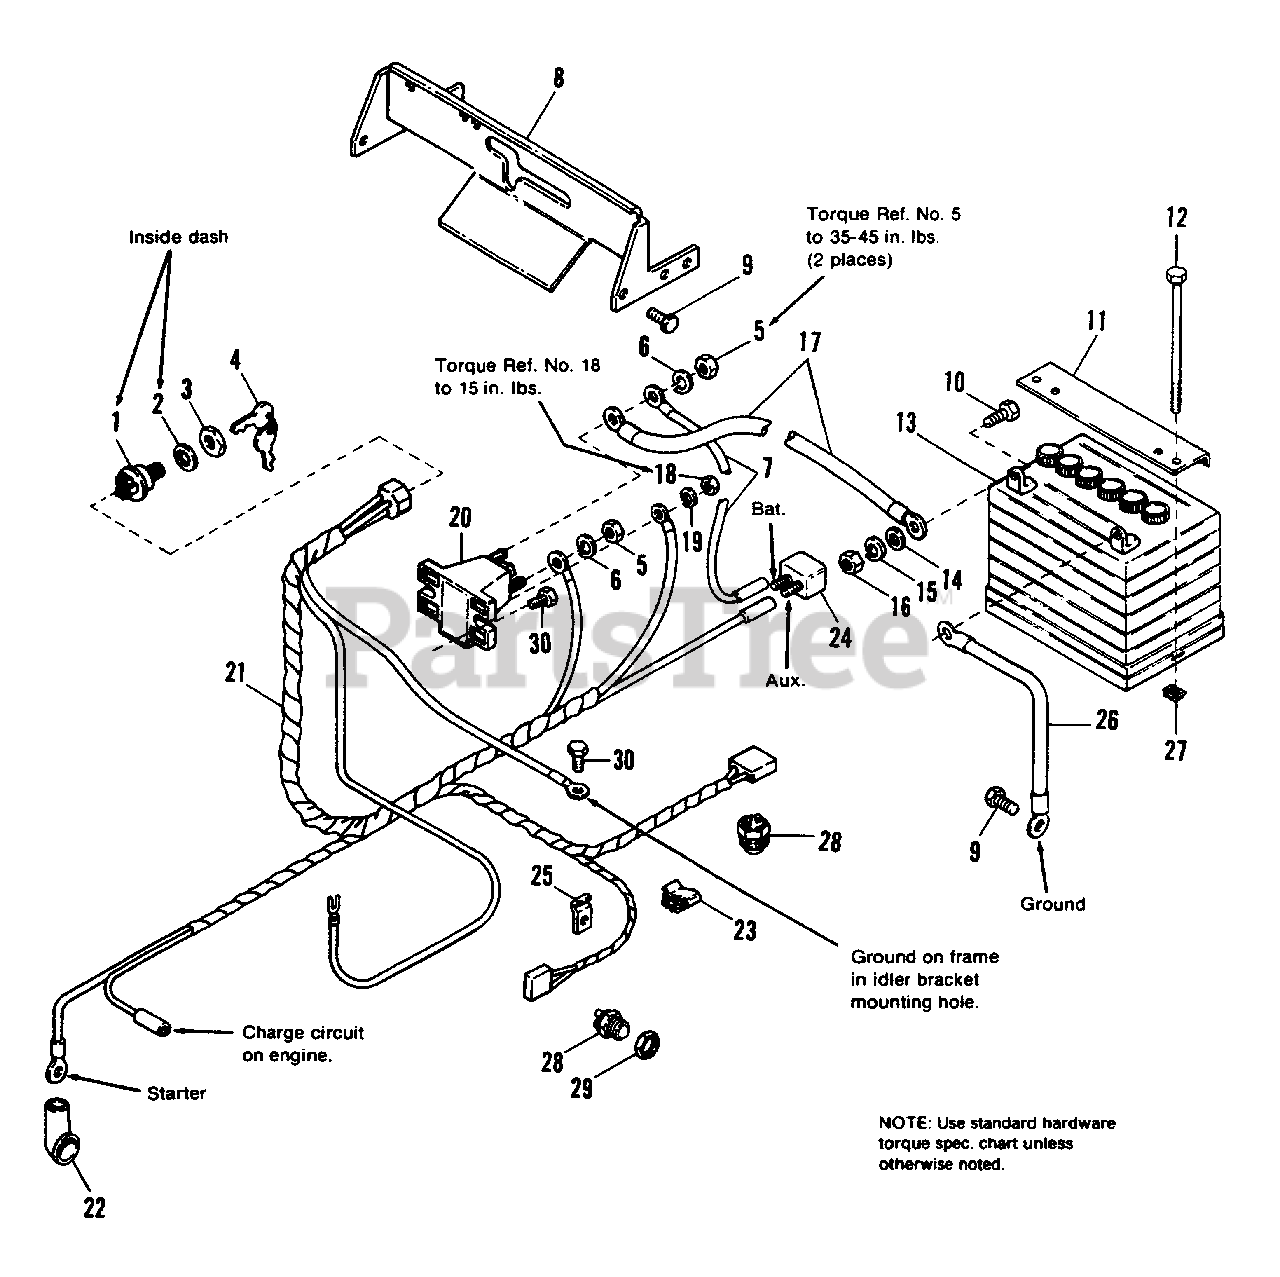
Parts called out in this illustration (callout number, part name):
1	SWITCH, Ignition
2	LOCKWASHER, Internal Tooth, 5/8
3	NUT, 5/8-32
5	NUT, Hex, 5/16-18
6	LOCKWASHER, 5/16
8	QUADRANT, Shift
9	SCREW, Taptite, 1/4-20 x 3/8
10	CAPSCREW, Hex, 1/4-20 x 3/4
11	CLAMP, Battery
12	CAPSCREW, Hex, 1/4-20 x 7-1/2
13	BATTERY SERVICE KIT
14	WASHER, 1/4
15	LOCKWASHER, 1/4
16	NUT, Hex, 1/4-20
18	NUT, Hex, #10-32
19	LOCKWASHER, Ext., #10
20	SOLENOID
21	HARNESS, Wiring
22	COVER, Terminal
23	CLIP, Speed
24	CIRCUIT BREAKER
27	NUT, Retainer, 1/4-20
28	SWITCH, PTO
29	LOCKNUT, 9/16-18
30	SCREW, Taptite, 1/4-20 x 5/8
